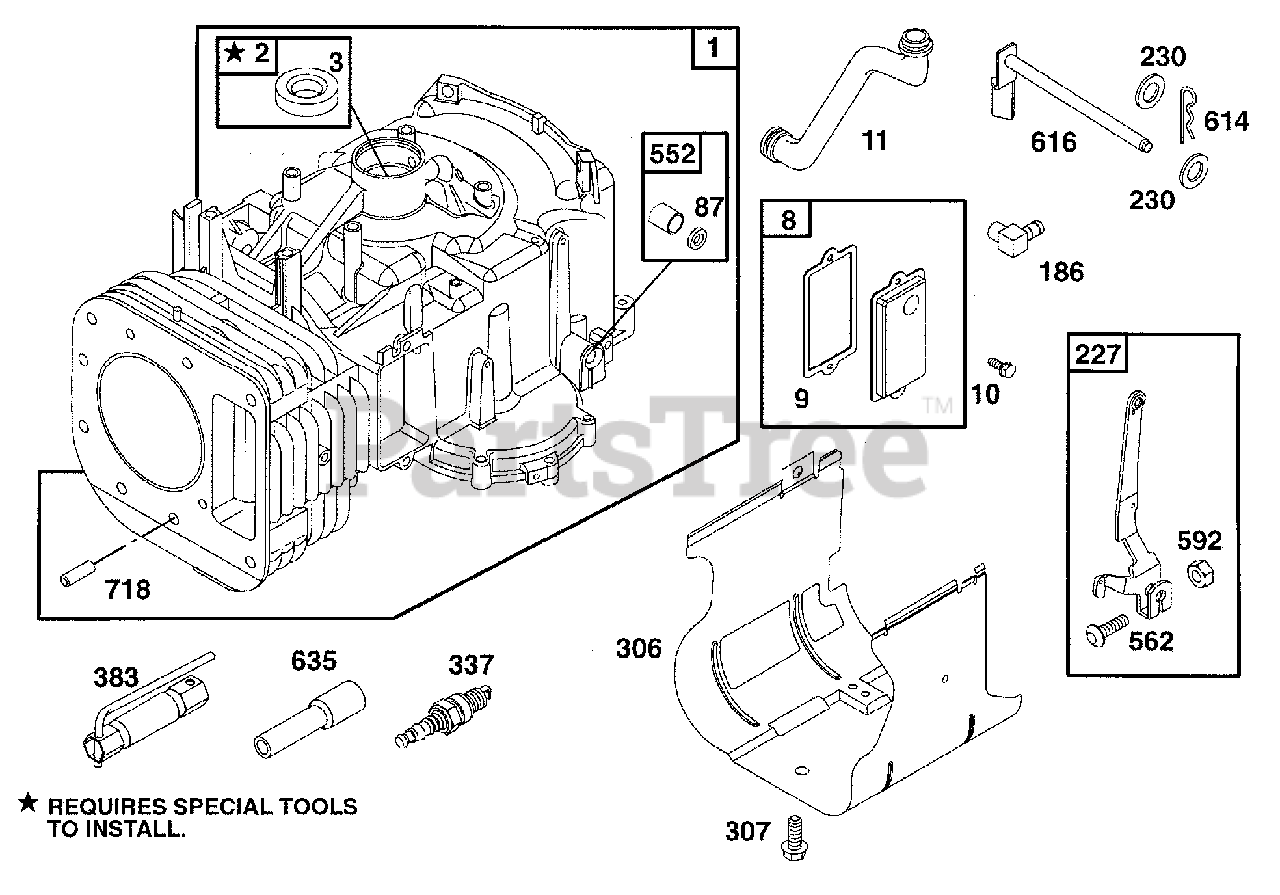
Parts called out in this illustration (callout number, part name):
1	Cylinder Assembly
2	Bushing/Seal Kit
3	Oil Seal
8	Breather Assembly
9	Breather Gasket
10	Hex Screw
11	Breather Tube
87	Governor Shaft Seal
186	Hose Connector
227	Governor Lever
230	Flat Washer
306	Cylinder Shield
307	Hex Screw
552	Governor Crank Bushing
562	Governor Lever Bolt
614	Cotter Pin
616	Governor Crank
635	Spark Plug Boot
718	Locating Pin
